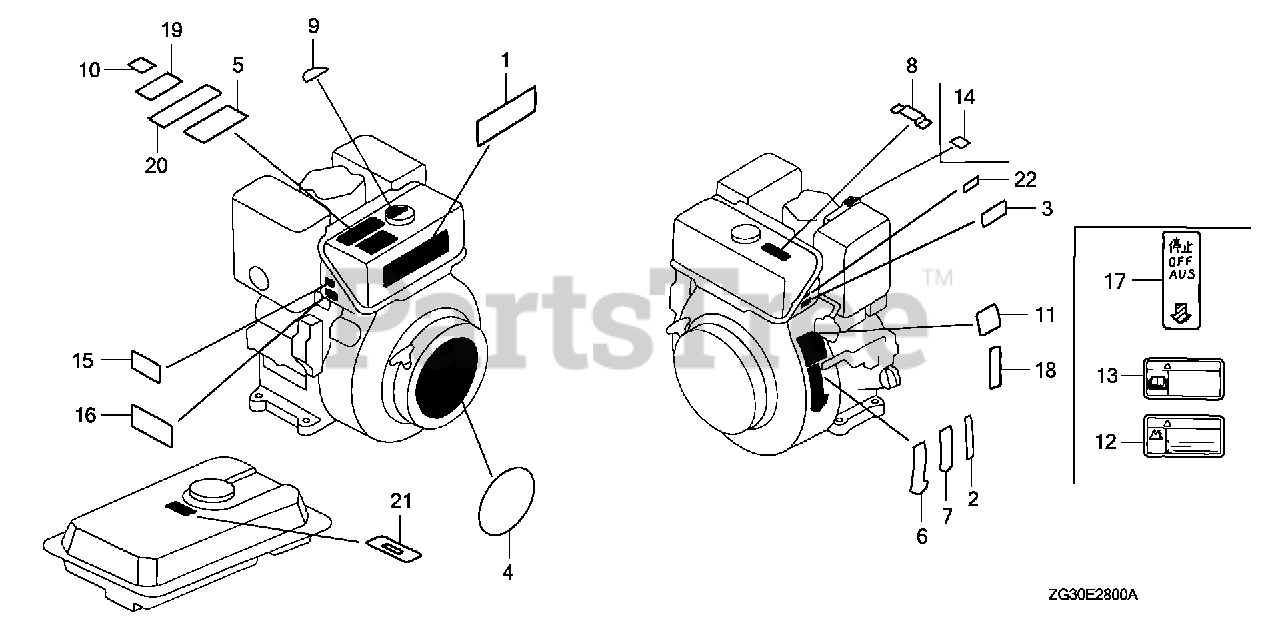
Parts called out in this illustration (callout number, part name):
1	EMBLEM (GD410)
5	LABEL, CAUTION(ENGLISH) (FRENCH)(GERMAN)(SPANISH)
6	MARK, THROTTLE (ENGLISH)
8	MARK, FUEL (EXTERNAL)
9	MARK, USE FUEL (ENGLISH)
11	MARK, OIL CAUTION (ENGLISH)
